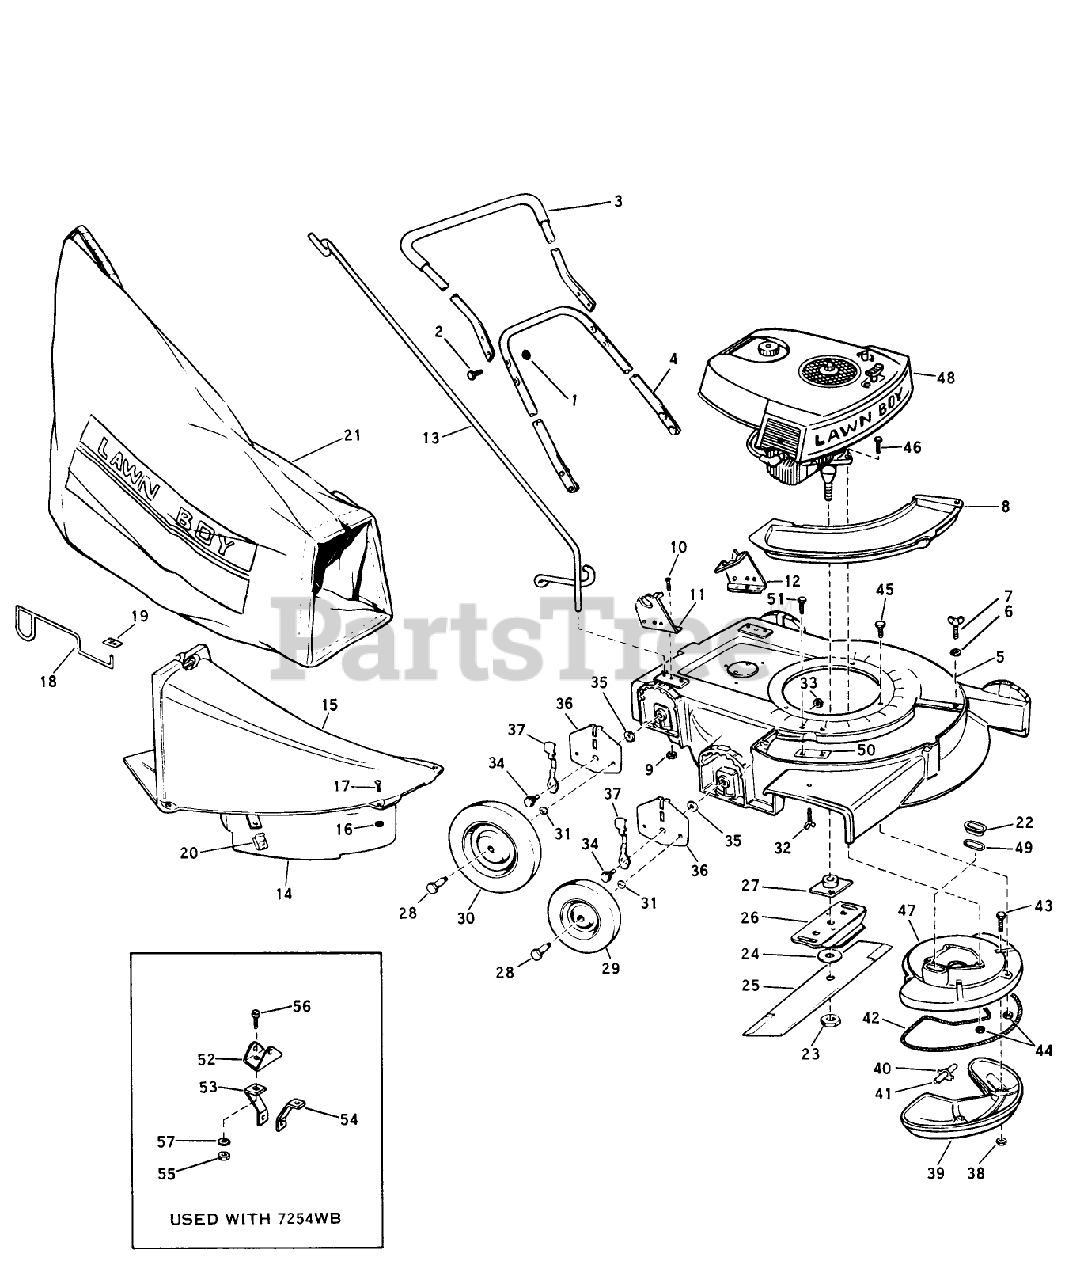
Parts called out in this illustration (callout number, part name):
1	STOP NUT
3	Handle Grip Assy. Top
5	Housing Cover Assy. 21"
10	SCREW S
14	Skirt Assembly-Chute (Includes Hardware)
15	Chute and Spring Assy. (Includes Hardware)
20	SPEED NUT ARDEN
21	89802 LB WHOLE GOODS
23	NUT-BLADE
27	PLATE AND COLLAR ASM
28	BOLT WHEEL
28	BOLT-SHOULDER
30	Wheel-Tire and Bearing (7254WB)
31	WASHER WROUGHT
38	LOCKNUT E
40	Gasket-Internal Tube
41	Tube-Internal Muffler
49	Gasket-Exhaust
53	Bracket-Mower Mounting
54	Bracket
55	STOP NUT
57	WASHER M
